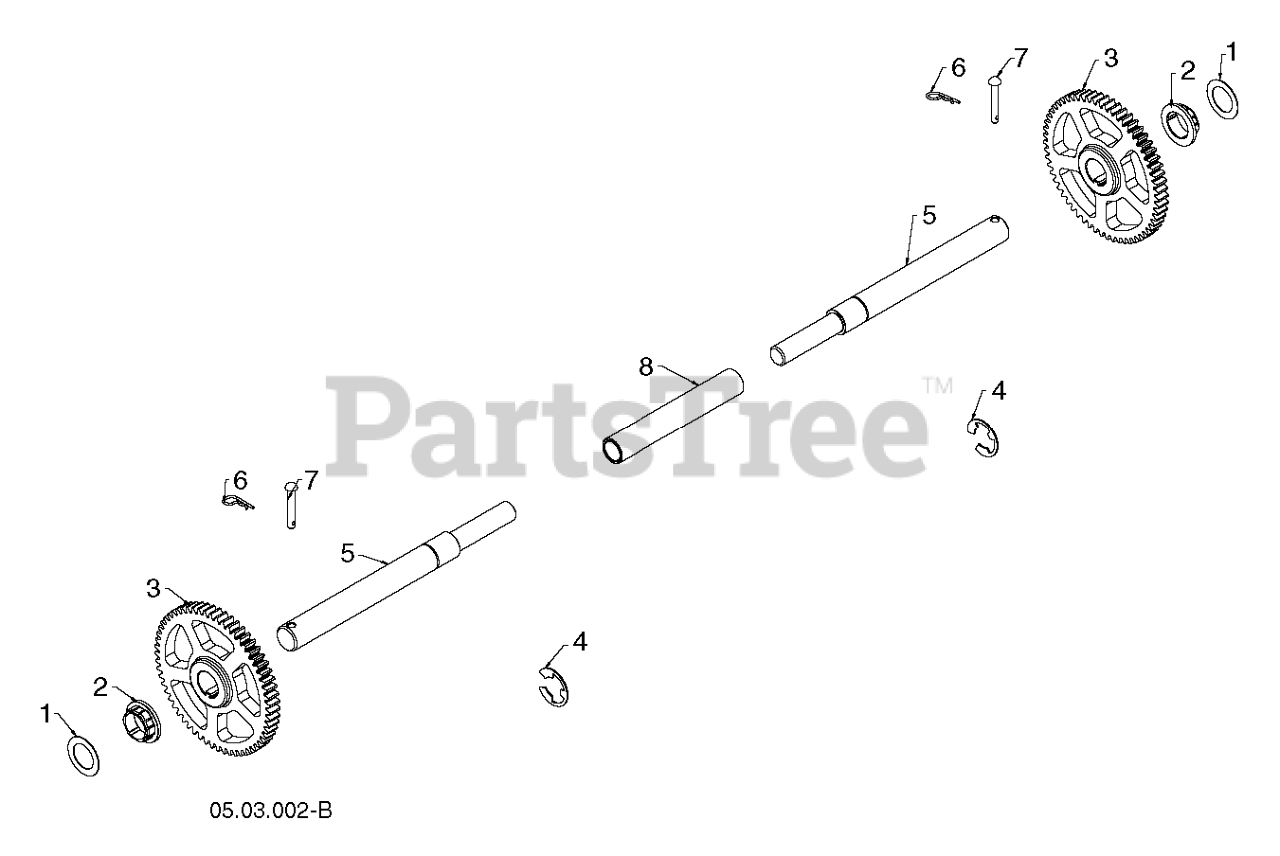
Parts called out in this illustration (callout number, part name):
1	STEERING WHEEL
2	FRONT AXLE ASSY
3	ZERK M
4	SPINDLE ASSY LH
5	SPINDLE ASM RH
6	THRUST WASHER
7	WASHER
9	CAP.SPINDLE.BLACK
10	BOLT, FIN HEX 5/8-11 X 2-3/4
11	TUBE, PIVOT AXLE
12	NUT, LOCK FLANGE 5/8-11 UNC
13	WASHER
14	WASHER
15	LOCK NUT
16	SHAFT ASM, STEERING
17	ROD ASSY/TIE BALL
18	DRAGLINK-BALL JOINT SOLID
19	SUPPORT ASM., STEERING VGT
21	STEERING WHEEL ADAPTOR
22	BUSHING, STRG. BLK
23	SCREW
24	WASHER 13/32 X 1-1/20 X 11 GA.
25	BOLT, FIN HEX 3/8-16 X 1 GR. 5
26	CAP.WHEEL.STEERING.GREY
27	BRNG T
28	SCREW
29	BEARING-FLANGE GT
30	Ring, Klip Truarc #5304-75
31	BUSHING.NYLINER.
32	WASHER 11/32 X 1 X 10 GA.
33	WASHER, LOCK HVY HLCL SPR 5/16
34	BOLT
35	GEAR.ASM.SECTOR.
36	TIE ROD
38	JOINT
41	BRACKET INTERLOCK
42	SCREW
46	NUT LOCK CENTER 3/8-24 UNF
